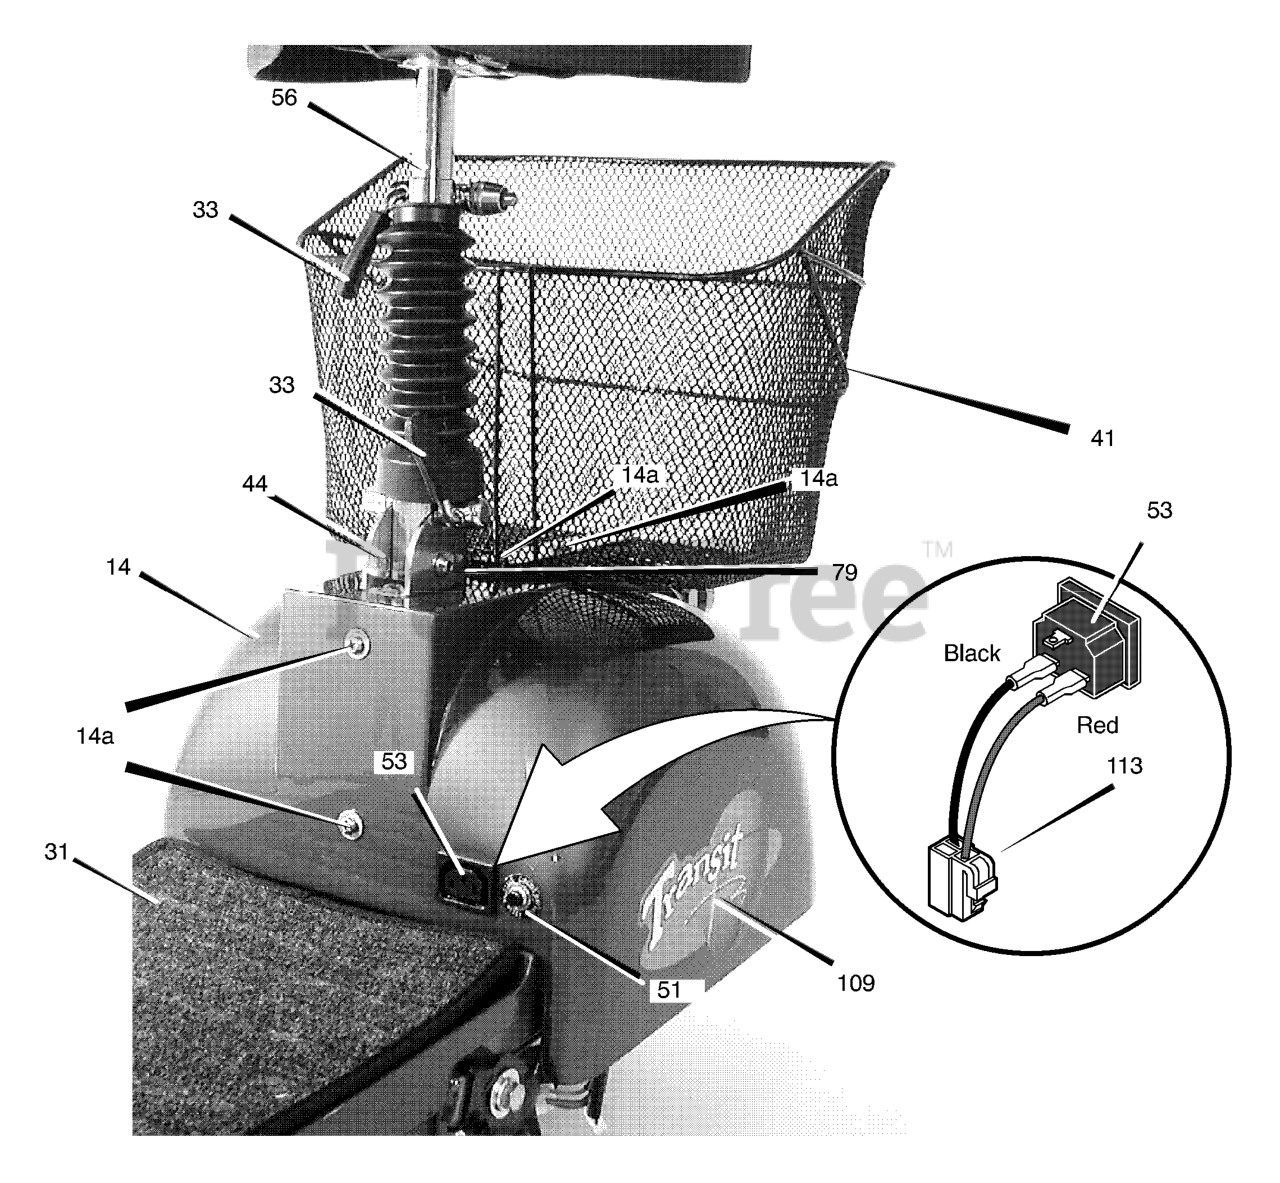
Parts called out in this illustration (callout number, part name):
14	Cover, Rear Wheel-with Decals
14A	Screw (4 required)
31	Floormat
33	Lever Ass'y., Quick Release
41	Basket-Black
44	Bracket, Seatpost Mounting
51	Circuit Breaker (20A)
53	Plug-in, Onboard Charging (requires gluing to Cover)
56	Seat Support Ass'y-Telescoping
79	Screw, Pivot
109	Decal, Transit
113	Harness, Wire-Onboard Charger Plug
